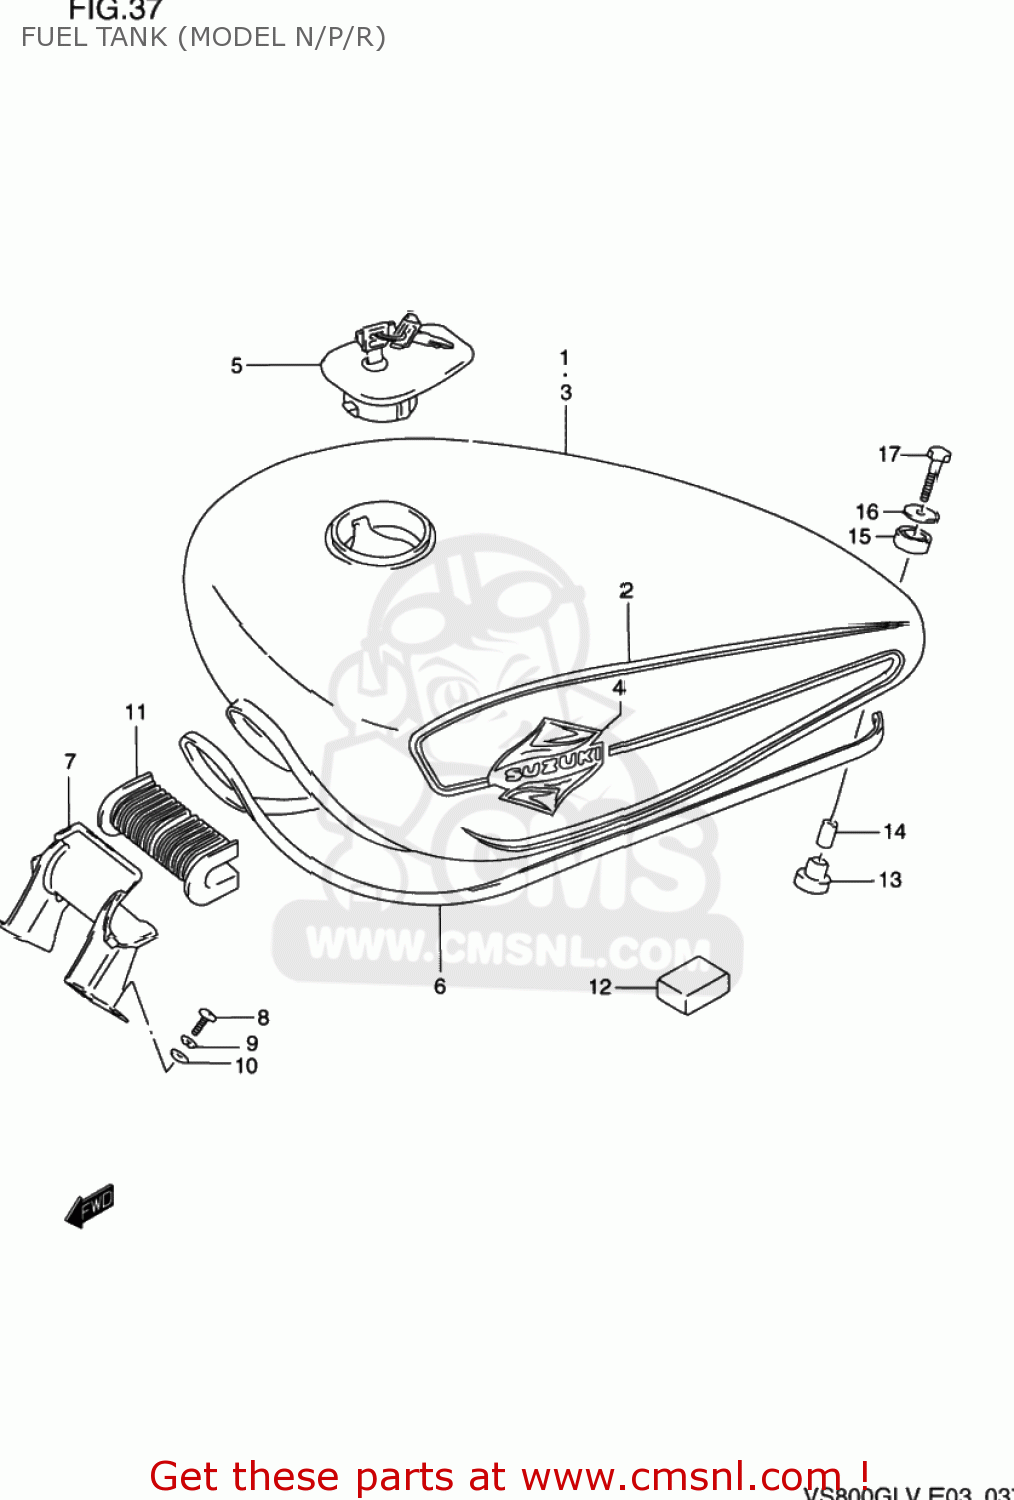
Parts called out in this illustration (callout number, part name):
1	TANK ASSEMBLY,FUEL
2	TAPE SET,FUEL TANK
3	TANK ASSEMBLY,FUEL
4	EMBLEM,FUEL TANK
5	CAP SET,FUEL TANK
6	MOLDING,FUEL TANK
7	BRACKET COMP,FUEL TANK
8	SCREW
9	WASHER,LOCK
10	WASHER
11	CUSHION,FUEL TANK FR
12	CUSHION
13	CUSHION
14	SPACER (6.4X9X21.5)
15	CUSHION
16	WASHER (6.5X24X1.6)
17	SCREW
